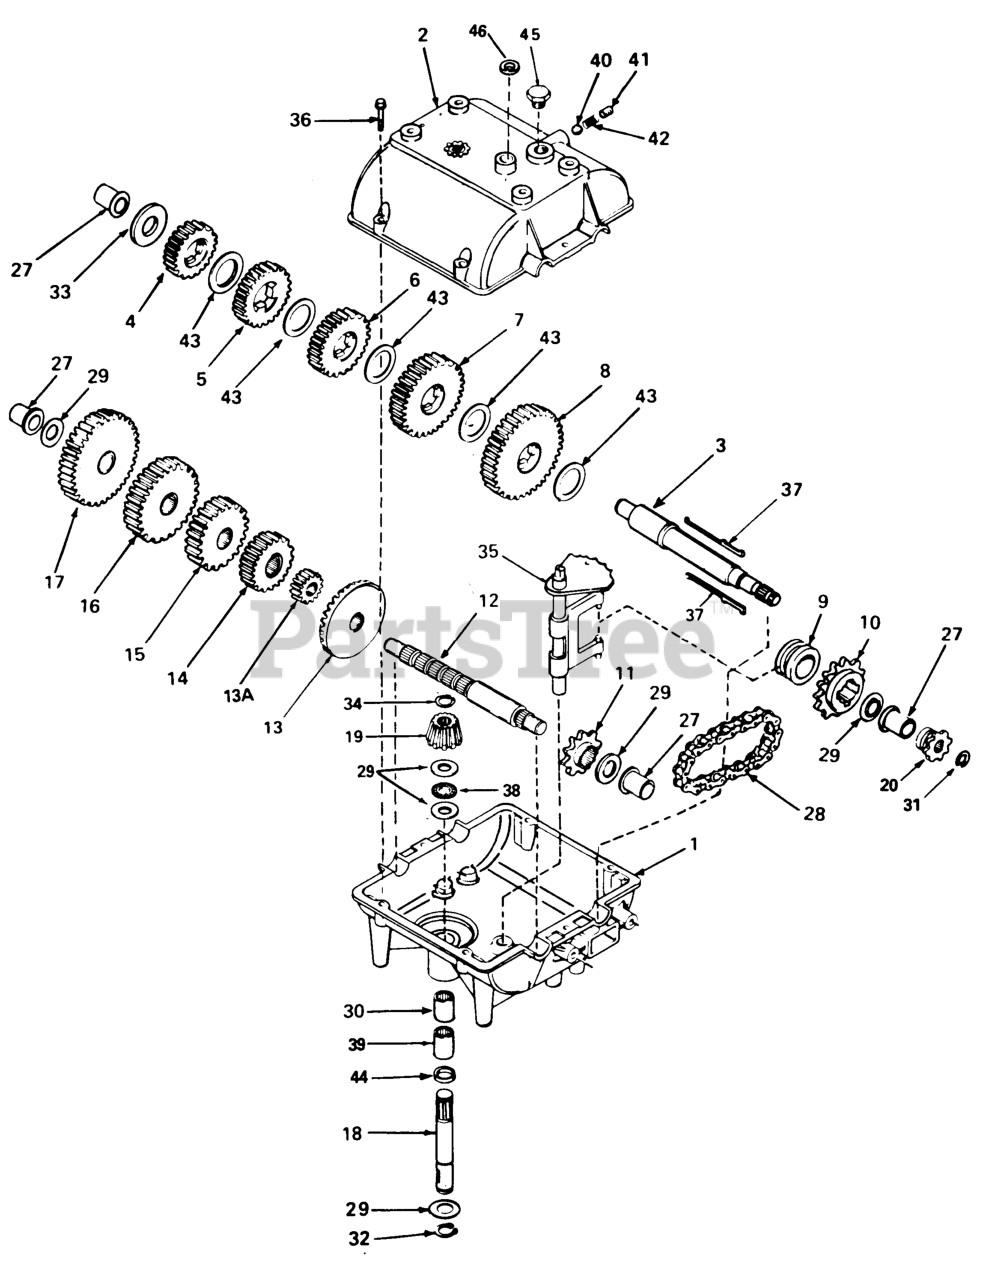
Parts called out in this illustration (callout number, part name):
1	Case, Transmission
2	Cover, Transmission
3	Shaft, Output
4	Gear, Spur (20 Teeth)
5	Gear, Spur (22 Teeth)
6	Gear, Spur (25 Teeth)
7	Gear, Spur (30 Teeth)
8	Gear, Spur (35 Teeth)
9	Collar, Shift
10	Sprocket (18 Teeth)
11	Sprocket (9 Teeth Sprocket)
12	Shaft, Counter
13	Bevel (42 Teeth)
13A	Gear, Spur (15 Teeth)
14	Gear, Spur (20 Teeth)
15	Gear, Spur (25 Teeth)
16	Spur (28 Teeth Gear)
17	Spur (30 Teeth Gear)
18	Shaft, Input
19	Bevel Pinion, Input
20	Sprocket (10 Teeth) (No. 40 Chain) (Ex P/N 603658)
27	Bushing, Flanged
28	Chain, Roller (No. 41 Chain, 24 Links)
29	Washer, Thrust
30	Bearing, Needle
31	Ring, Retaining
32	Ring, Retaining
34	Ring, Retaining
35	Rod & Fork Assy., Shift
36	Screw, Flanged Hex Hd. Thr'd Forming 1/4-20 X 1-1/4
38	Bearing, Thrust
39	Bearing, Needle
40	Ball, Steel, 5/16"
41	Screw, Set 3/8-16 X 3/8
43	Washer, Thrust
44	Seal, Oil
45	Plug, Threaded
46	Seal, Square Cut
